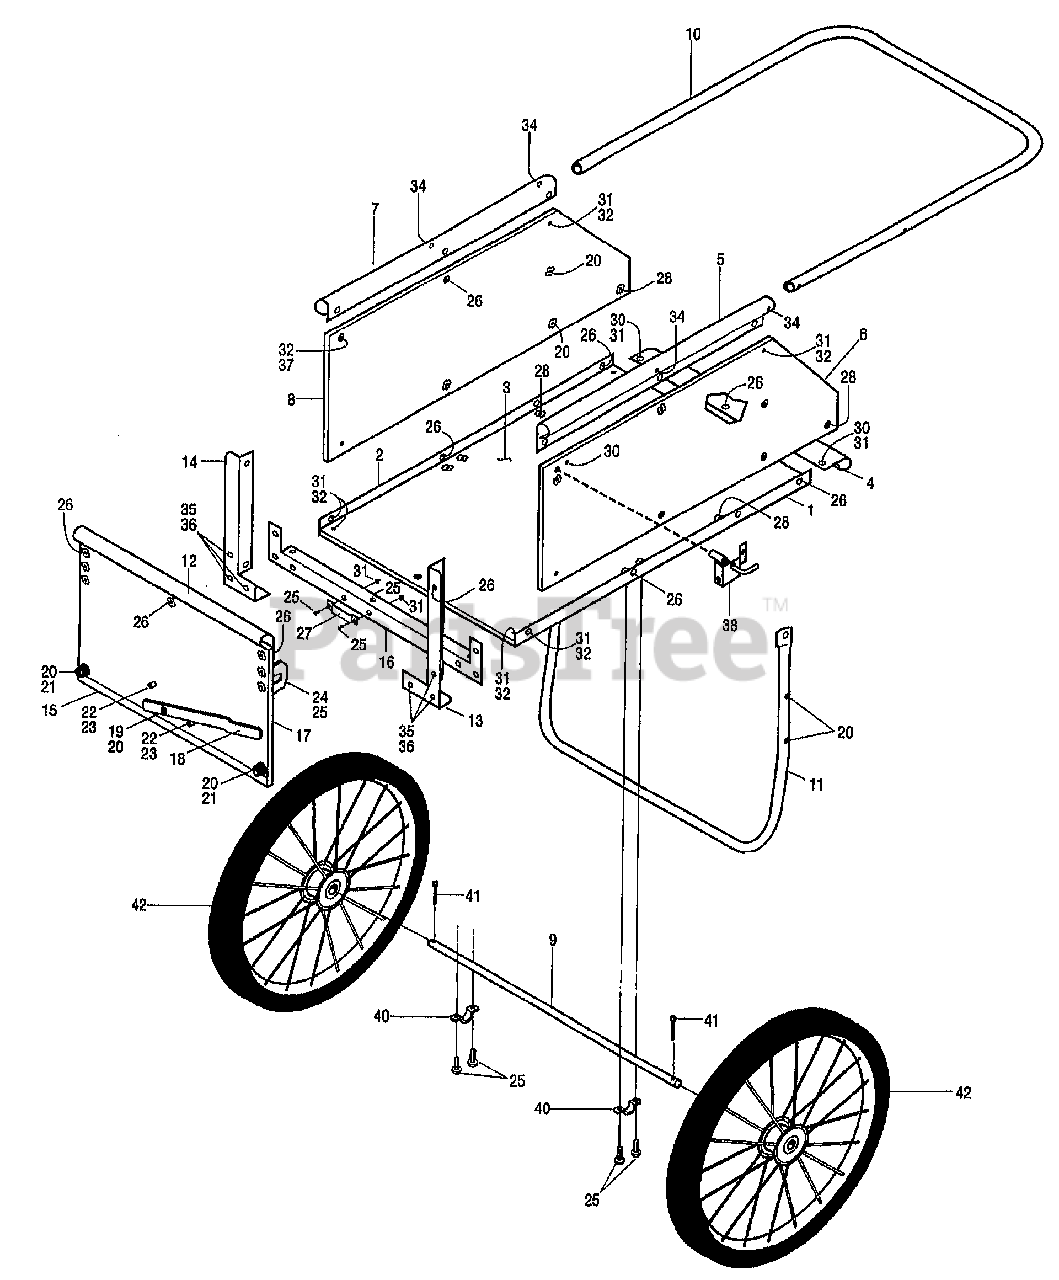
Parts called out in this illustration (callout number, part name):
1	ANGLE-BOTTOM 20 SOLID FRONT LT
2	ANGLE-BOTTOM 20 SOLID FRONT RT
3	PANEL-BOTTOM W/TNUTS
4	PROTECTOR-REAR M20
5	SLEEVE-20 HANDLE LT
6	PANEL-LFT W/TNUTS M20
7	SLEEVE-20 HANDLE RT
8	PANEL-RH W/TNUTS M20
9	AXLE-MODEL 20
10	MISC 20 HANDLE
11	STAND-M20 SF/DF
12	PROTECTOR-20 TOP EDGE
13	SUPT-20 SWING FRONT SIDE LT
14	SUPT-20 SWING FRONT SIDE RT
15	EDGE-BOTTOM M20
16	SUPT-BOTTOM 20 SWING FRONT
17	PANEL-FRONT DOOR W/TNUTS
18	LATCH-20&26 SWING FRONT
19	SPACER-20&26 SWING FRONT
20	BOLT-1/4 X 1 1/4 PAN HD
21	CASE FEET
22	BUSHING-.31X.188X.38
23	SCR-WOOD RHS M8X.75 ZP
24	HINGE-20&26 SWING FRONT
25	BOLT-1/4 X 5/8 PAN HD
26	SCR-PH 1/4-20 X .5
27	PLATE-LATCH 20&26 SWING FRONT
28	NUT-HT/LK 1/4-20X.375
30	BOLT-SLPH 1/4-20 X.875-ZP
31	NUT-LK 1/4-20
32	BOLT-1/4 X 1 PAN HD
34	SCR-PHS M6X.5 ZP
35	SCR-HH 5/16-18X.5 GD5 YEL
36	NUT-H/LK 5/16-18 NYLOCK
37	PIVOT-HINGE M26 R/D
38	ASSM-20&26 PLUNGER
40	CLAMP-AXLE 20 & 26
41	PIN-COTTER 3/32 X 1 1/4
42	WHEELS-T/B M20 CART BOX 2
